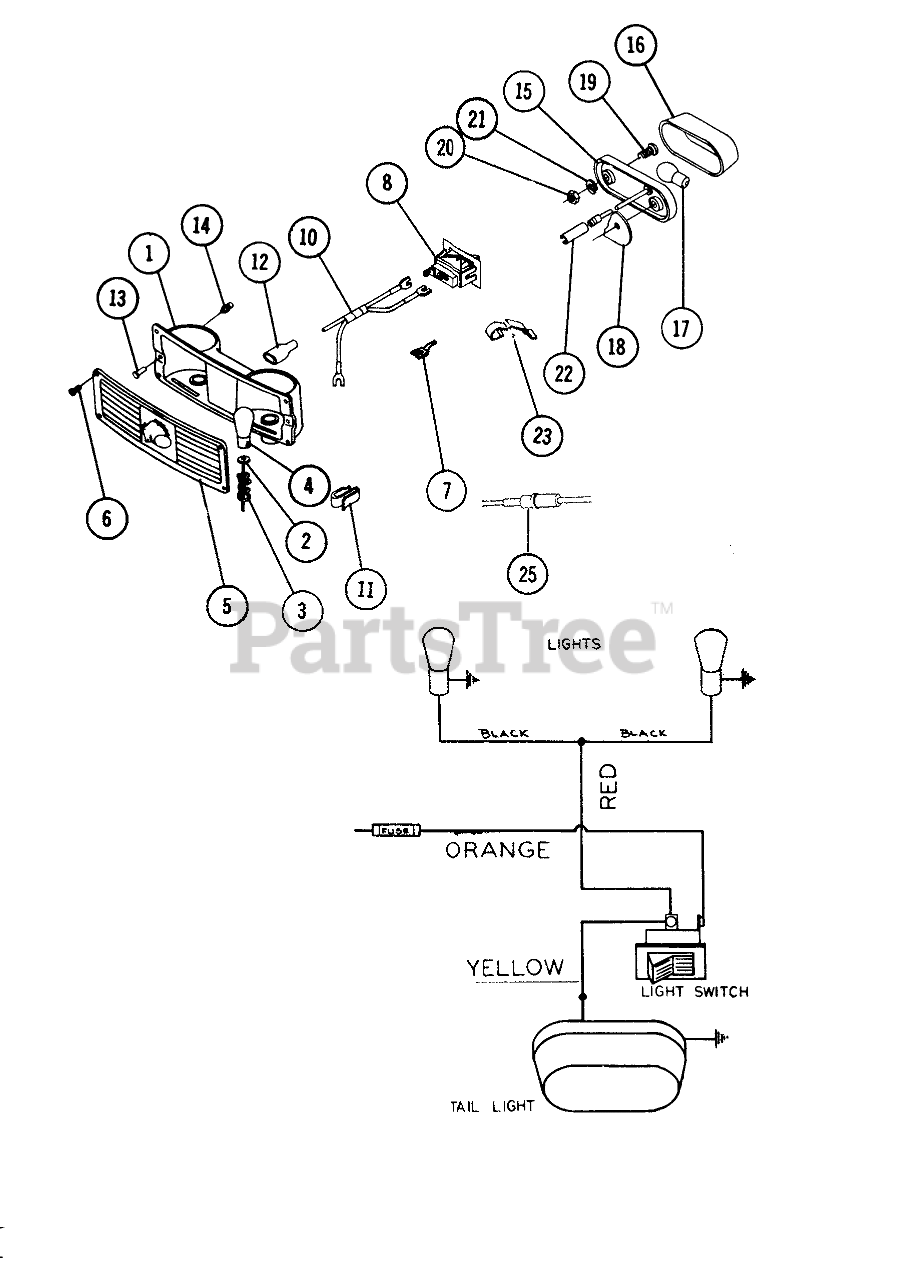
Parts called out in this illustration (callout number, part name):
1	ASSY REFLECTOR HOUSI
2	WIRE ASSY
3	SPRING
4	BULB
5	Lens
6	Screw S. T. 6-32 x 5/8
7	Spade Terminal
8	SWITCH-LIGHTS
10	Tine RH
11	SPEED CLIP
12	CONNECTOR 3 WIRE
13	Rivet 1/8 x 3/8 Flat Head
14	Nut 1/8 Dia.
15	Base
16	Lens
17	Bulb
18	Mounting Pad
19	Bolt-Pan Head #10-32 x 7/8
20	Nut #10-32
21	Lockwasher #10
22	CONNECTOR 2 WIRE
23	CLIP-WIRE
25	Tine Bolt
NS	Terminal
NS	Sur-Plug
